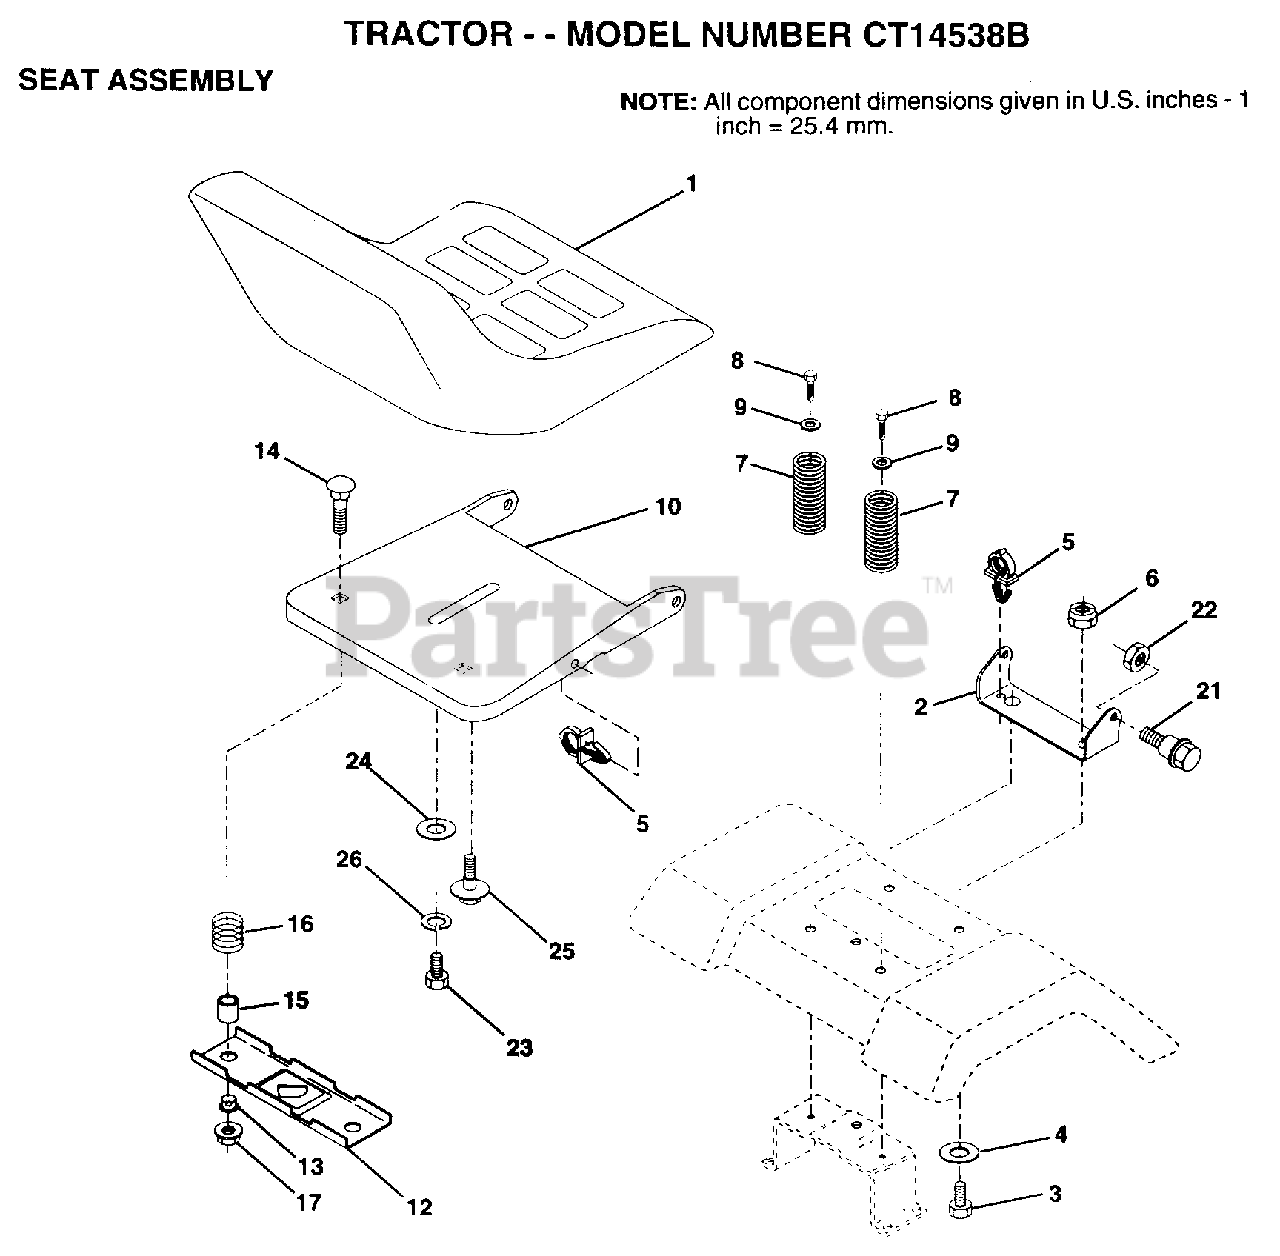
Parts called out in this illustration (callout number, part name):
2	BRACKET PVT SEAT
3	BOLT
4	WASHER PM
5	CLIP.PUSH-IN.HING
6	NUT
7	SPRING COMPRESSIO
8	SCREW GTV
9	WASHER
12	BRKT SWITCH
13	BUSHING
15	SPLIT SPACER
16	SPRING
21	"BOLT,SHOULDER"
22	NUT
23	BOLT
24	WASHER
25	"BOLT,SHOULDER"
26	LOCKWASHER
